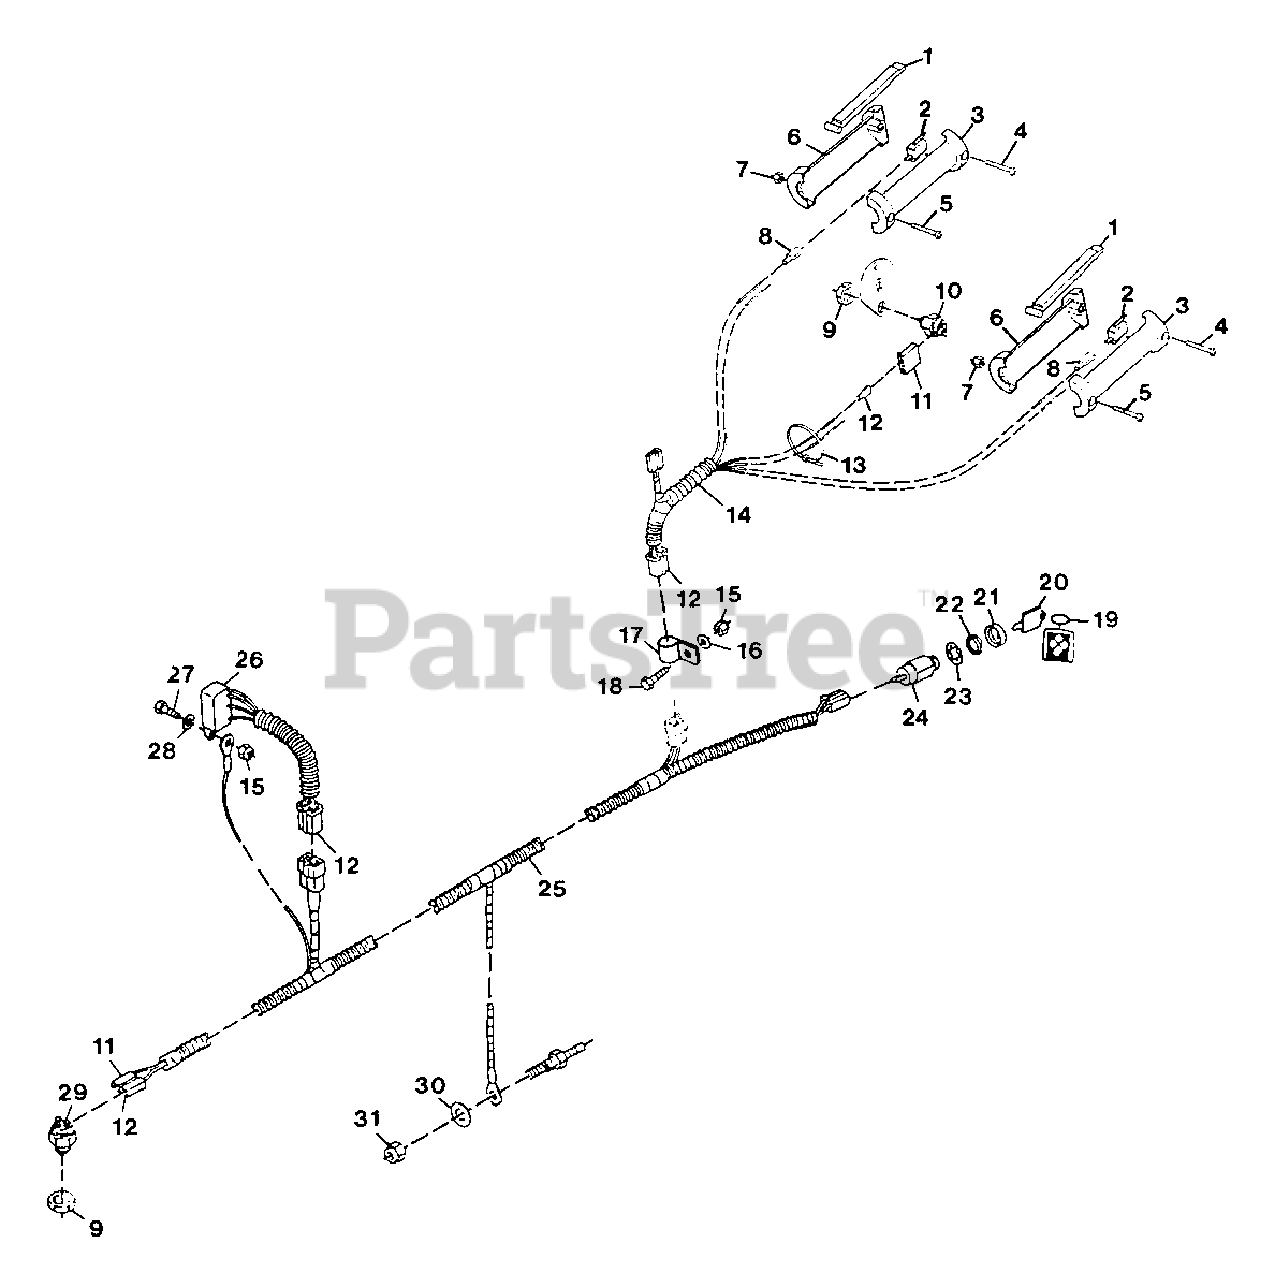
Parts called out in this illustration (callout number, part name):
1	Lever
2	Switch
3	Handle, L.H.
4	Screw, Machine 10-24x.625 PHD
5	Screw, Machine 10-24x1.50 PHD
6	Handle, R.H.
7	Nut, Lock 10-24
8	Terminal, Female
9	Nut, Stamped 9/16-18
10	Switch, Neutral Start
11	Connector, 2-Wire Switch
12	Terminal
13	Tie Wrap, Black
14	Harness, Wiring Handlebar
15	Nut, Lock 1/4-20
16	Washer, Flat .281x.625x.065
17	Clamp, Nylon
18	Bolt, Hex 1/4-20x.75
19	Chain, Key
20	Key, Ignition Switch
21	Boot
22	Nut, 9/16-24
23	Washer, Lock 5/8 Int. Tooth
24	Switch
25	Harness, Wiring
26	Module, Interlock Recoil
27	Bolt, Hex 1/4-20x.625
28	Washer, Lock 1/4 Int. Th.
29	Switch, Interlock
30	Washer, Flat .469x.938x.065
31	Nut, Lock 3/8-16
